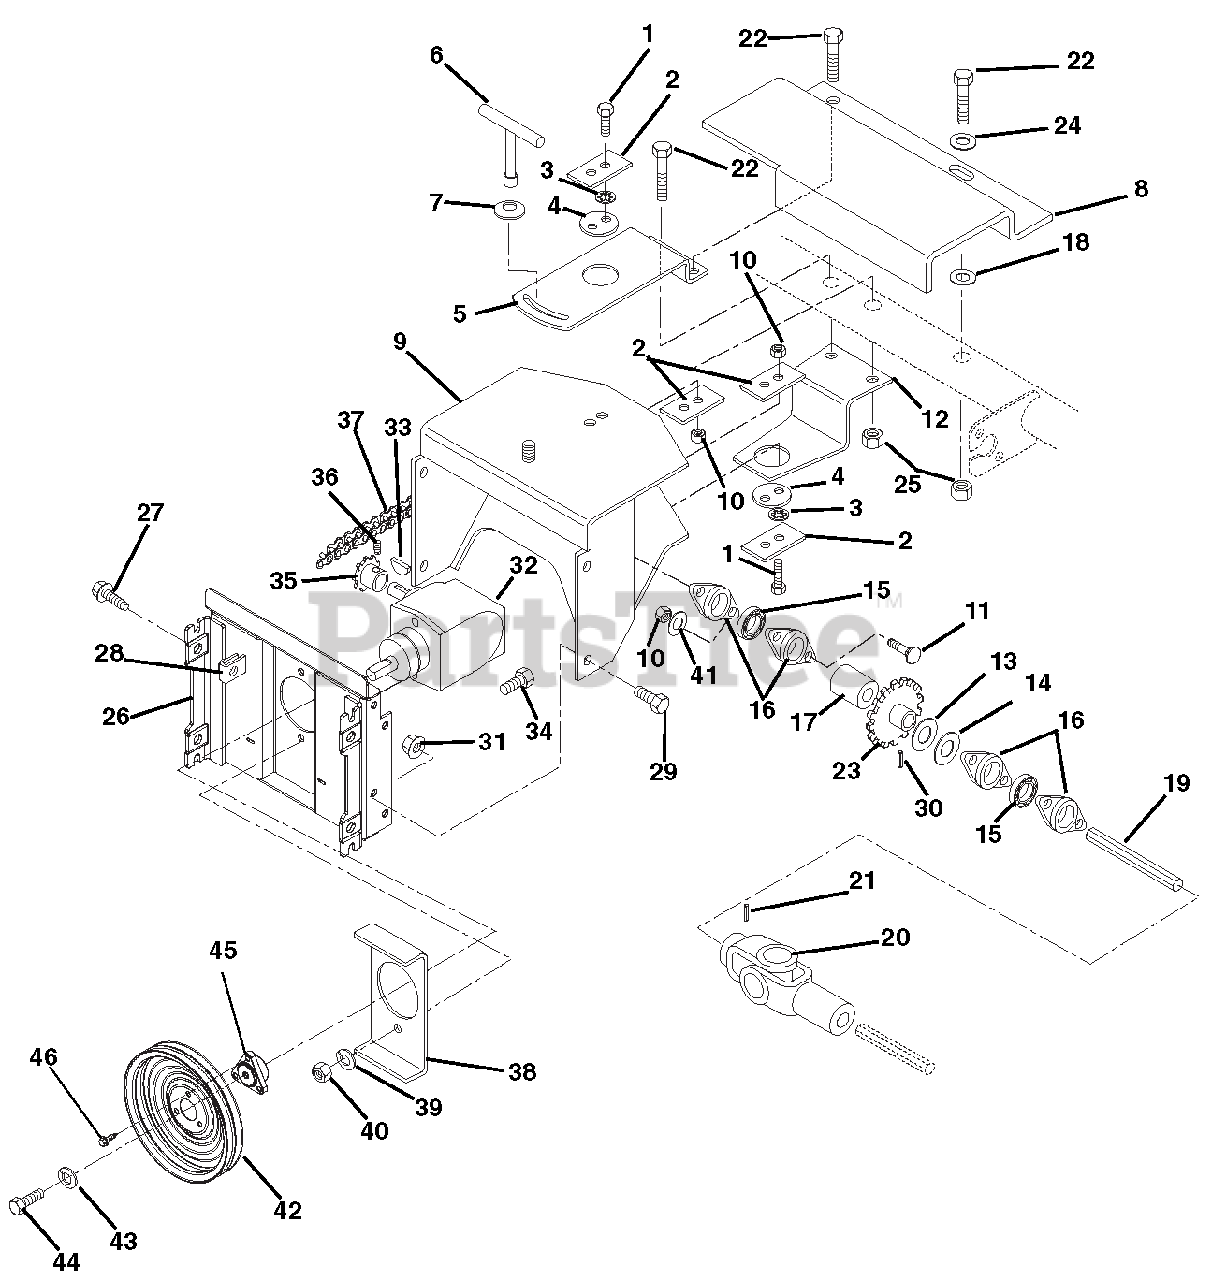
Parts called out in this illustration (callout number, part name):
1	@BLT-HEX .31-18X1.25 GR5 YWZC
2	RETAINER
3	@WSHR-LK-EXT.326X.599X.031YWZC
4	PIVOT CENTER
5	PLATE, TOP MOUNT
6	T-LOCK HANDLE
7	WSHR-BLVL .669X1.535X.138
8	GUARD, SHAFT
9	FRAME, ADAPTOR
10	@NUT-LK-CTR .31-18 YWZC
11	@BLT-RDHDSQNK .31-18X.75 G5YZ
12	PLATE, BOTTOM MOUNT
13	WSHR-FL-STL 1.031X1.625X.188
14	WSHR-FL-STL 1.03X1.31X.105
15	BRG-BALL .884HEXX52MMX1.07
16	BEARING FLANGE
17	SPACER 1.006X1.307X.500
18	WSHR-FL-STL .390X.88X.18 YWZC
20	JOINT, UNIVERSAL
21	PIN-ROLL .188X1.50
22	@BLT-HEX .38-16X3.25 GR5 YWZC
23	SPROCKET
24	@WSHR-FL-STL.406X.812X.065 YWZ
25	@NUT-LK-CTR .38-16 YWZC
26	PLATE, MOUNTING-BROOM
27	BLT-SERHFWH .38-16X.75 YWZC
28	NUT-RTNR .375-16X.37
29	@BLT-HEX .38-16X.75 GR5 YWZC
30	PIN-ROLL .188X1.75
31	@NUT-LK-CTR .38-16 YWZC
32	GEAR BOX ASSEMBLY
33	KEY-WDRF .188X.75X.313 SAE 9
34	@BLT-HEX .38-16X1.25 GR5 YWZC
35	SPROCKET
36	SCR-SET .25-20X.38 SKHCUPNL OH
37	ROLLER CHAIN #41 - 34 PITCHES
38	PLATE, STIFFENER
39	@WSHR-LK .38X.094 REG YWZC
40	@NUT-HEX .38-16 YWZC
41	@WSHR-FL-STL.38X.875X.083 YWZC
42	PULLEY, SPIN FORM DUAL GROOVE
43	WSHR-LK .312X.097 HVY YWZC
44	BLT-HEX .31-24X.75 YWZC GR5
45	PULLEY HUB, D-BORE .87 PRO
46	@SCR-TAP .31-18X.50 HWH TR YWZ
